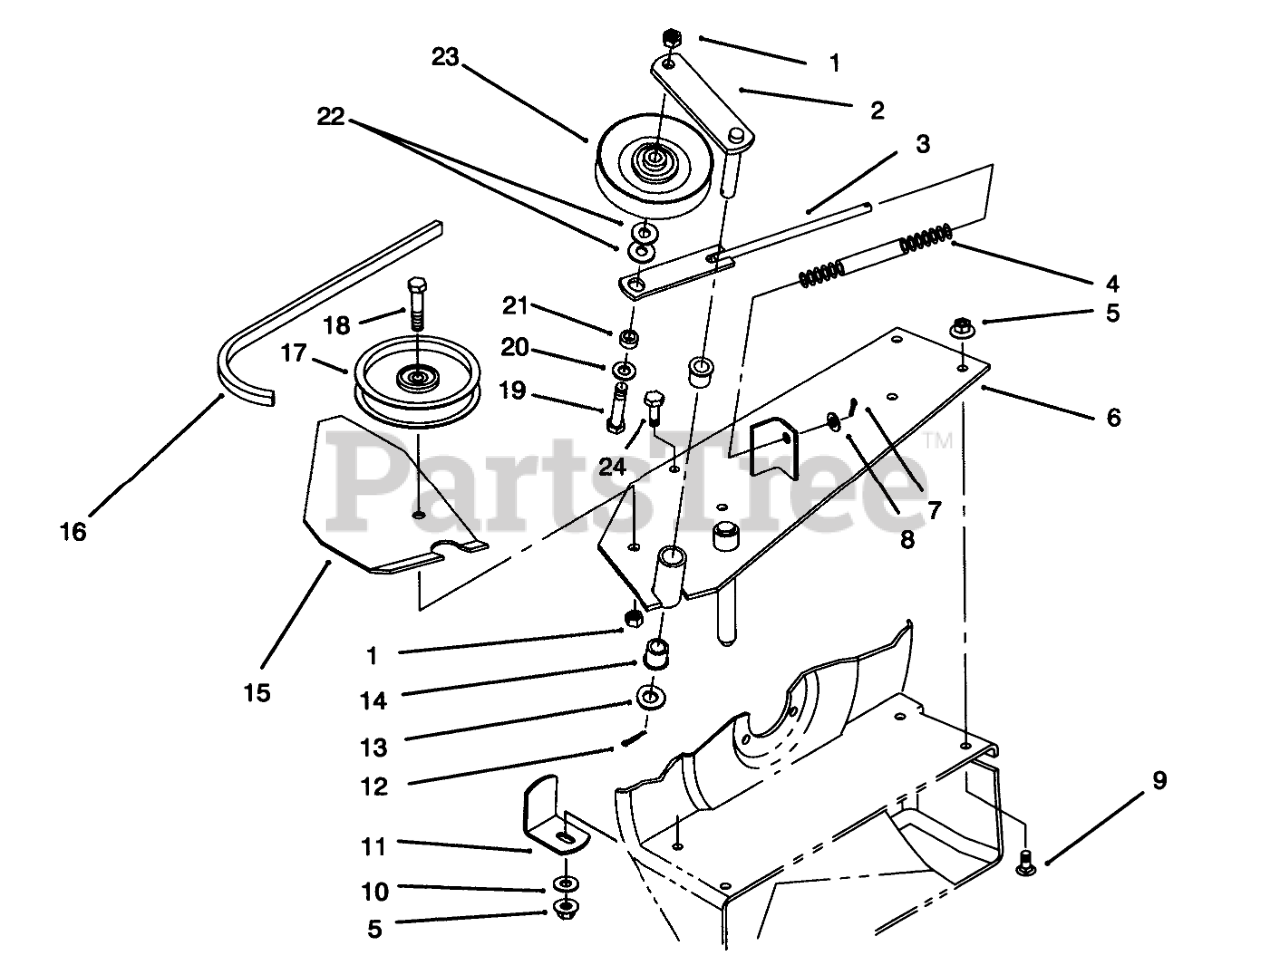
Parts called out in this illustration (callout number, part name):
1	NUT-LOCK, NI
2	IDLER ARM ASM
3	SPRING-ROD
4	SPRING-COMPRESSION
5	NUT-HF
6	BLOWER-MTG ASM
7	PIN-COTTER
8	WASHER-PLAIN
9	BOLT-CARR
10	WASHER-FLAT
11	BRACKET-SUPPORT, HOUSING
12	PIN-COTTER
13	WASHER-FLAT
14	BUSHING
15	SHIELD SUPPORT B
16	V-BELT
17	PULLEY-IDLER
18	SCREW-HH
19	SCREW-HH
20	WASHER-FLAT
21	SPACER
22	WASHER-FLAT
23	PULLEY-IDLER
24	SCREW-HH
